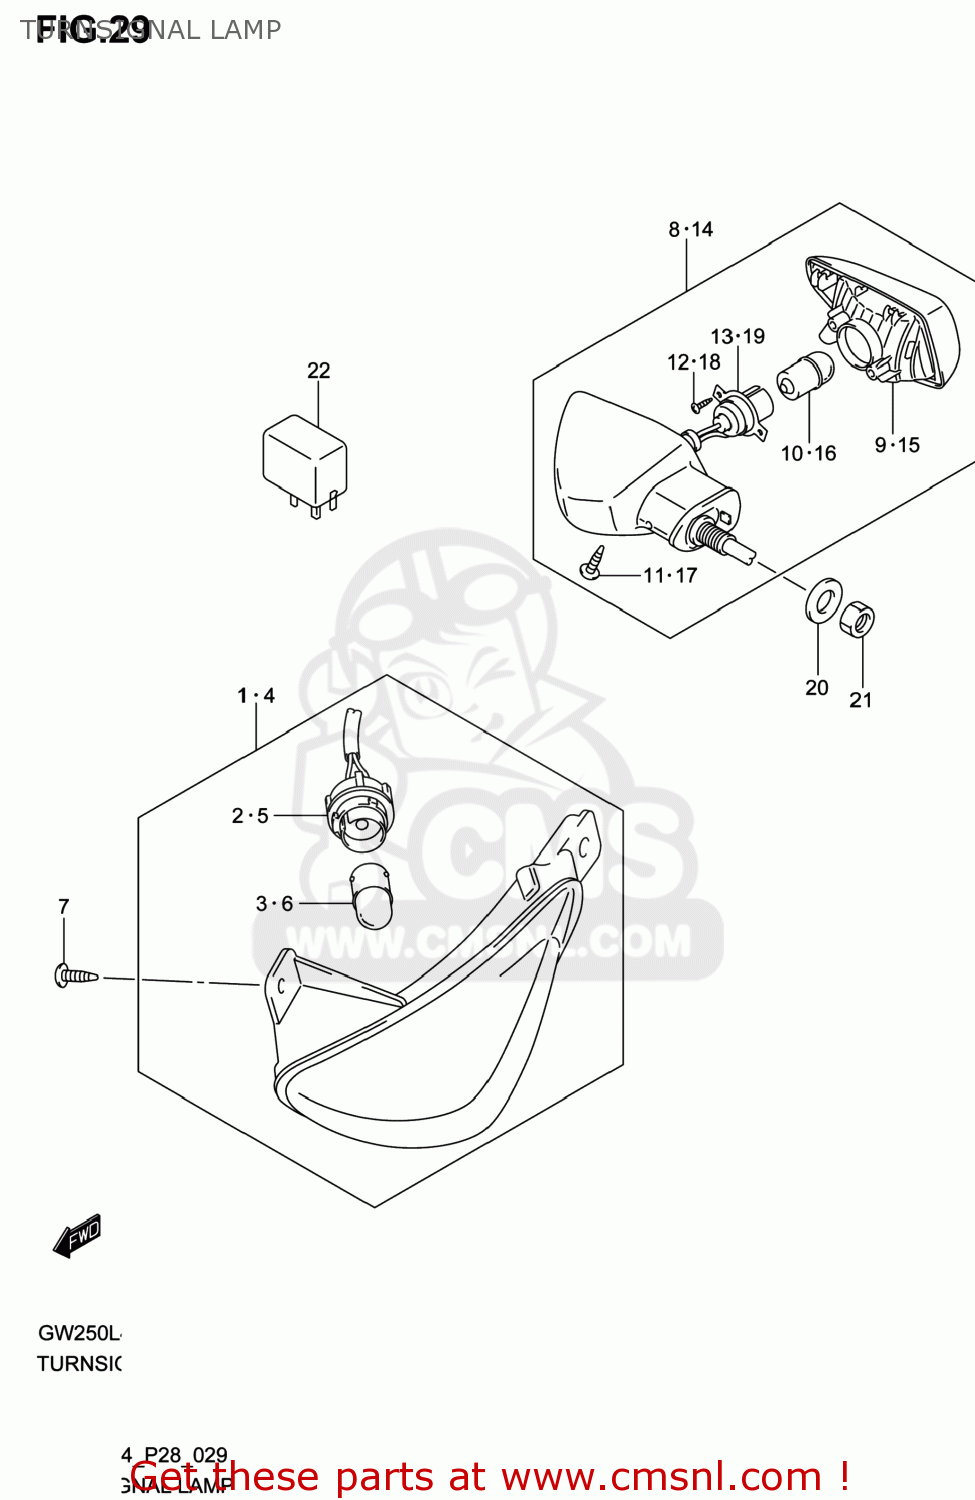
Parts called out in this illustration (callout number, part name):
1	LAMP ASSY,FR TURN SIGNAL,R
2	CORD
3	BULB(12V10W,AMBER)
4	LAMP ASSY,FR TURN SIGNAL,L
5	CORD
6	BULB(12V10W,AMBER)
7	SCREW
8	LAMP ASSY,RR TURNSIGNAL,R
9	LAMP UNIT,R
10	BULB(12V10W,AMBER)
11	SCREW
12	SCREW
13	CORD,R
14	LAMP ASSY,RR TURNSIGNAL,L
15	LAMP UNIT,L
16	BULB(12V10W,AMBER)
17	SCREW
18	SCREW
19	CORD,L
20	WASHER,RR TURNSIGNAL LAMP
21	NUT
22	RELAY ASSY,TURNSIGNAL LAMP
